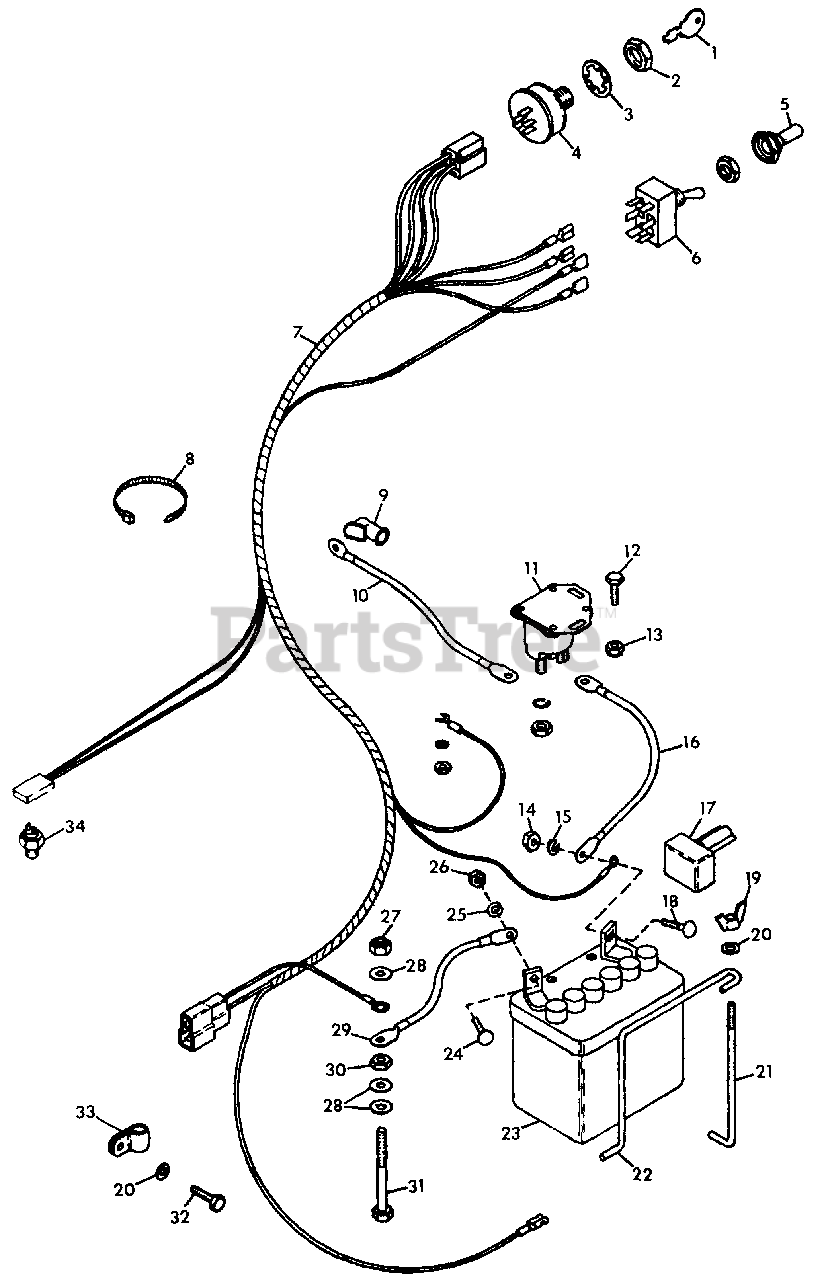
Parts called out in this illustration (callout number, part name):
1	KEY, IGNITION SWITCH
2	NUT, JAM 9/16-24
3	WASHER, LOCK 9/16
4	SWITCH, IGNITION
5	BOOT, TOGGLE SWITCH
6	SWITCH, TOGGLE
7	HARNESS, WIRING
8	TIE, CABLE
9	BOOT, BATTERY CABLE
10	CABLE, SOLENOID TO STARTER
11	SWITCH, MAGNETIC
12	BOLT, HEX 1/4-20X.625
13	NUT, SPEED 1/4-20
14	NUT, HEX 5/16-18
15	WASHER, LOCK 5/16 REG.
16	CABLE, BATTERY TO SOLENOID
17	BOOT, BATTERY CABLE
18	BOLT, 5/16-18X.625 RD HD SQ NK
19	NUT, WING 1/4-20
20	WASHER, FLAT .281X.625X.065
21	HOOK, BATTERY HOLD DOWN
22	BRACKET, BATTERY HOLD DOWN
23	BATTERY, 12 VOLT
24	BOLT, 1/4-20X.625 RD HD SQ NK
25	WASHER, LOCK 1/4
26	NUT, HEX 1/4-20
27	NUT, LOCK 5/16-18
28	WASHER, FLAT .344X.688X.065
29	CABLE, NEGATIVE BATTERY
30	NUT, HEX 5/16-18
31	BOLT, HEX 5/16-18X2.00
32	BOLT, HEX 1/4-20X1.00
33	CLAMP
34	SWITCH, NEUTRAL START
